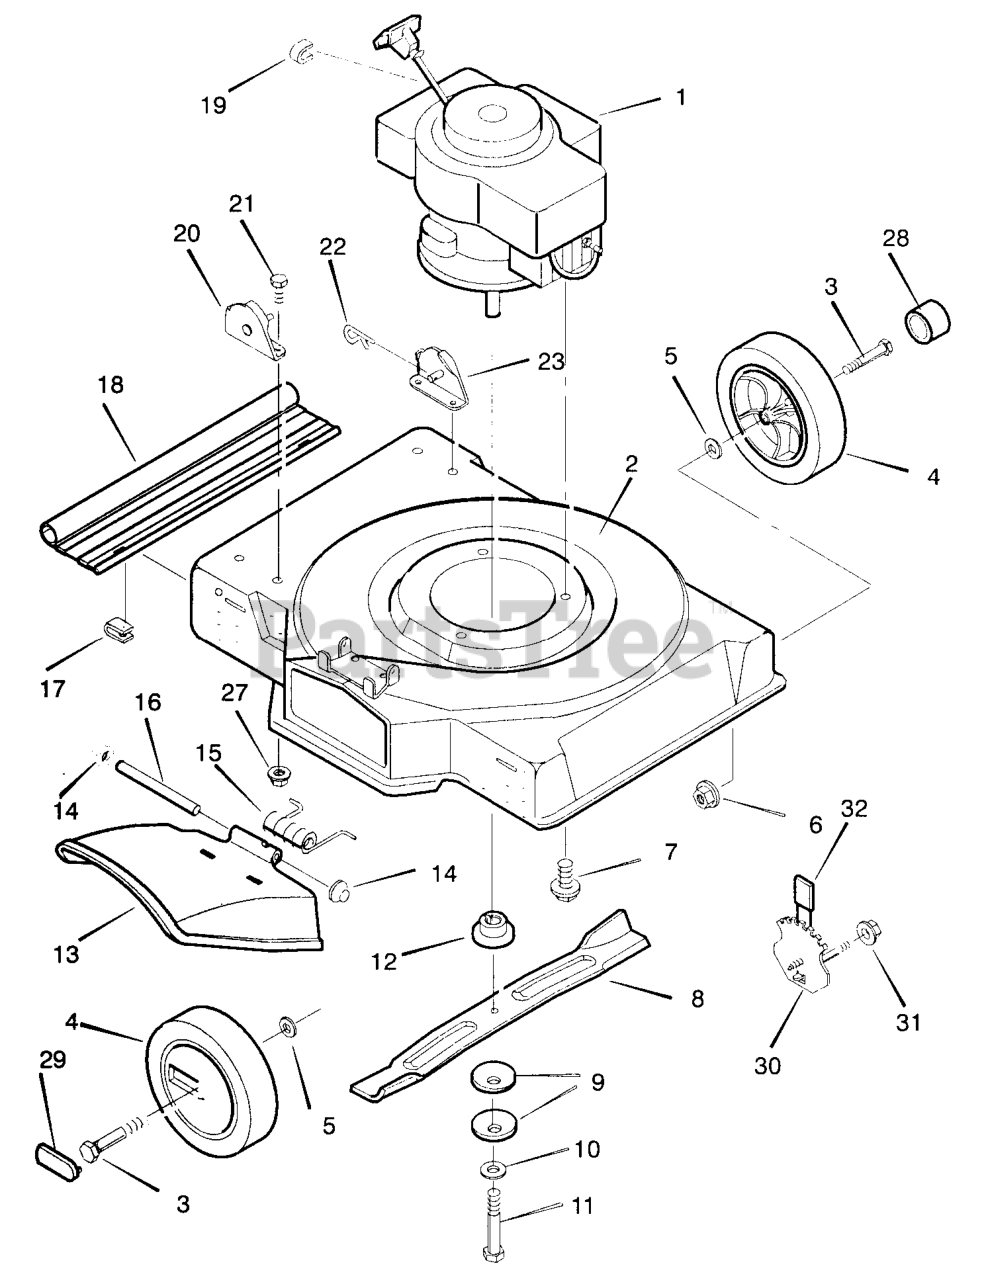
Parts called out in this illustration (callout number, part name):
1	Engine *
2	Housing, For Folding Handle
3	Bolt, Axle
4	Wheel and Tire *
6	Locknut, Flange
7	Bolt, Engine
9	Washer, Belleville
11	Bolt, Hex
12	Adapter, Blade
13	Deflector, Chute
14	Push-On Cap
16	Pin, Pivot
17	Retainer
18	Deflector, Rear
19	Stop, Rope
20	Bracket, Right Handle
22	Pin, Hair
23	Bracket, Left Handle
27	Nut
28	Hub Cap
29	Hub Cap
30	Adjuster, Height
31	Locknut, Flange
